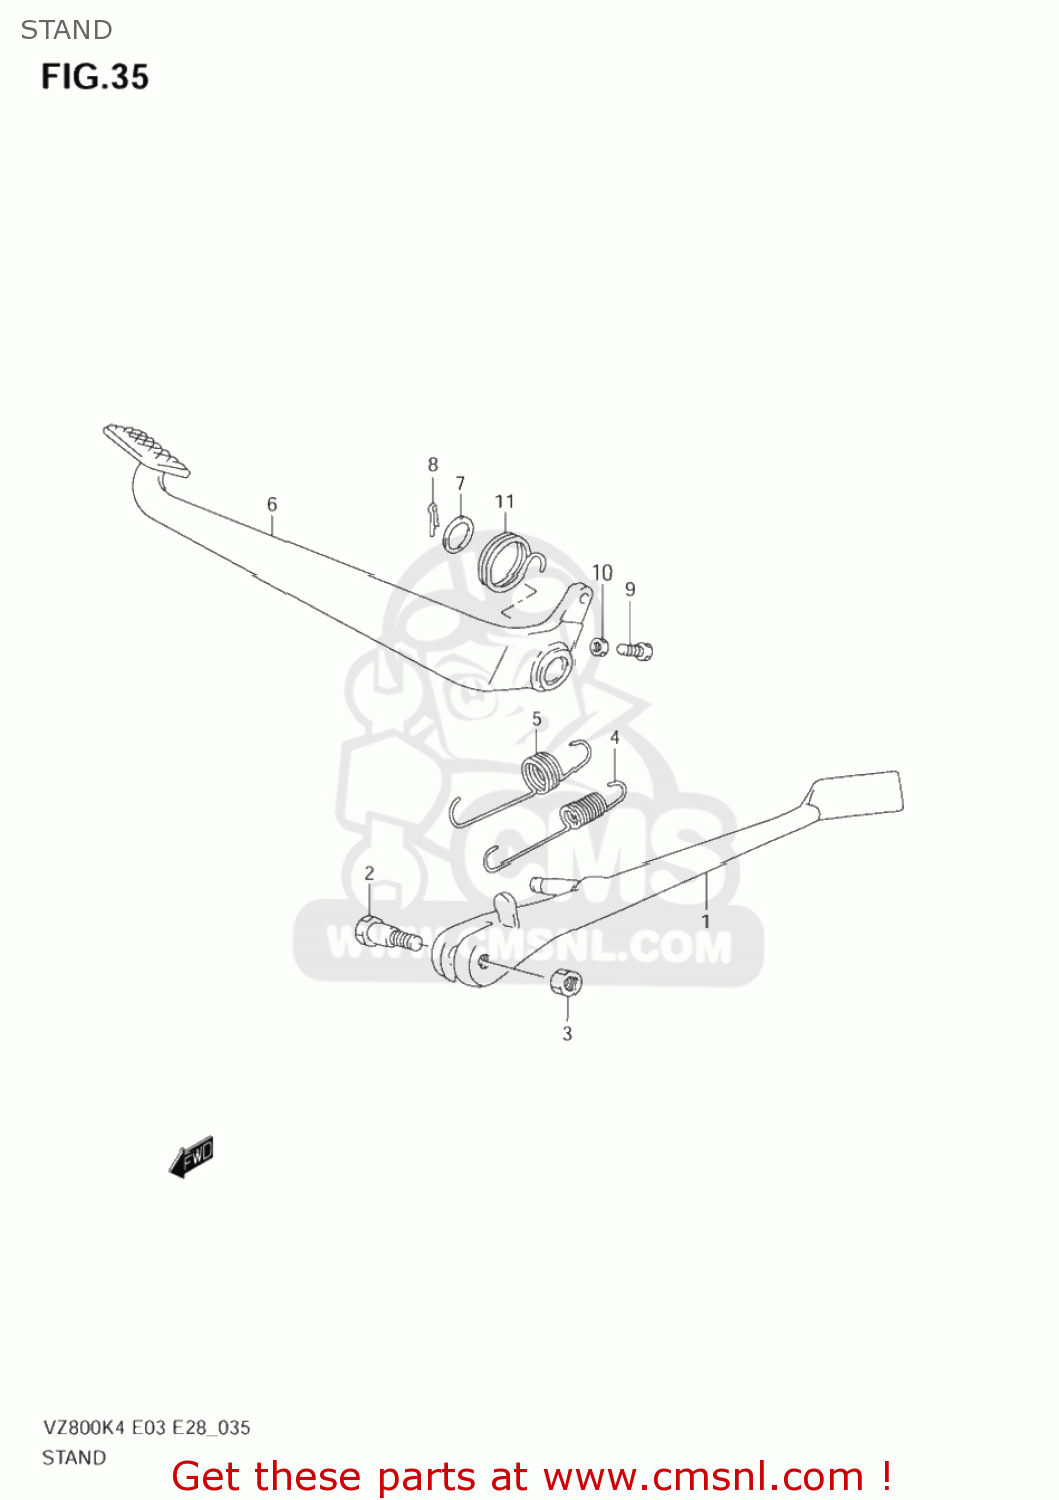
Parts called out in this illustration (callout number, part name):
1	STAND,PROP
2	BOLT(10X34)
3	NUT
4	SPRING
5	SPRING
6	PEDAL,BRAKE
7	WASHER(16.5X22X1)
8	COTTER PIN
9	BOLT
10	NUT
11	SPRING
